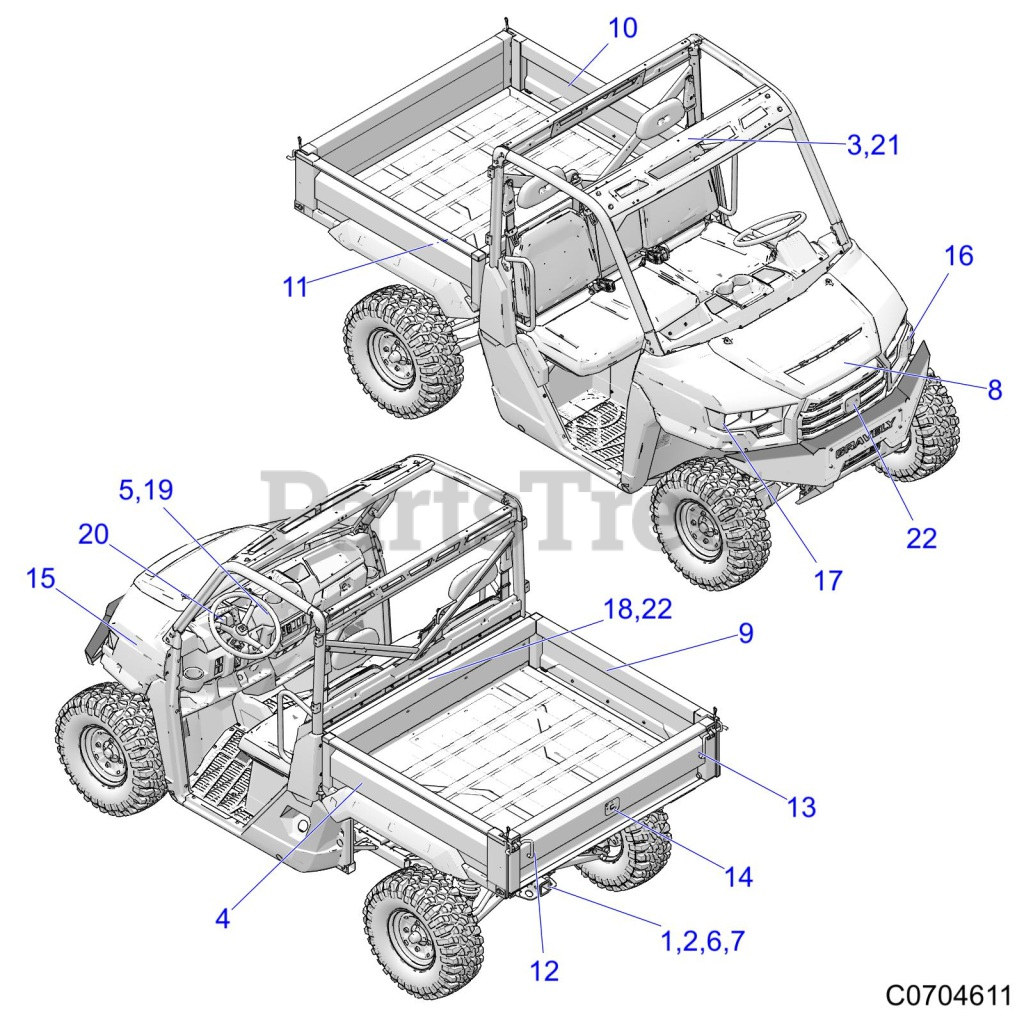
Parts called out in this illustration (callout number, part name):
1	DECAL-TIE DOWN,LH
2	DECAL, REFLECTOR RED
3	DECAL-WARN,SEATBLT/COML/RIDERS
4	DECAL, BOX SIDE GRAVELY
5	DECAL-START,STOP
6	DECAL-WARN,HOT/HITCH,2500LBS
7	DECAL-TIE DOWN,RH
8	DECAL-COOLANT
9	DECAL-WARN,NEVER CARRY FUEL
10	DECAL-BOX,SIDE,3400SD,LH
10	DECAL-BOX,SIDE,JSV3200,LH
10	DECAL-BOX,SIDE,JSV3400,LH
11	DECAL-BOX,SIDE,3400SD,RH
11	DECAL-BOX,SIDE,JSV3200,RH
11	DECAL-BOX,SIDE,JSV3400,RH
12	DECAL-TAILGATE,ARNS,STL,LH
12	DECAL-TAILGATE,ARNS,POLY,LH
13	DECAL-TAILGATE,ARNS,STL,AWD,RH
13	DECAL-TAILGATE,ARNS,POLY,LH
13	DECAL-TAILGATE,ARNS,PLY,4X2,RH
14	DECAL, TAILGATE GRAVELY CENTER
14	DECAL-TAILGATE,ARNS,CNTR,POLY
15	DECAL-FENDER,SIDE,ARNS,LH
15	DECAL-FENDER,SIDE,ARNS,RH
16	DECAL, REFLECTOR AMBER LH
17	DECAL, REFLECTOR AMBER RH
18	DECAL-WARN,PASS/TIRE,ARNS
19	DECAL-CAUTION,SHIFT
20	DECAL-WARN,PAYLOAD,ARNS
21	DECAL-WARN,PROPER USE, 3 OC
